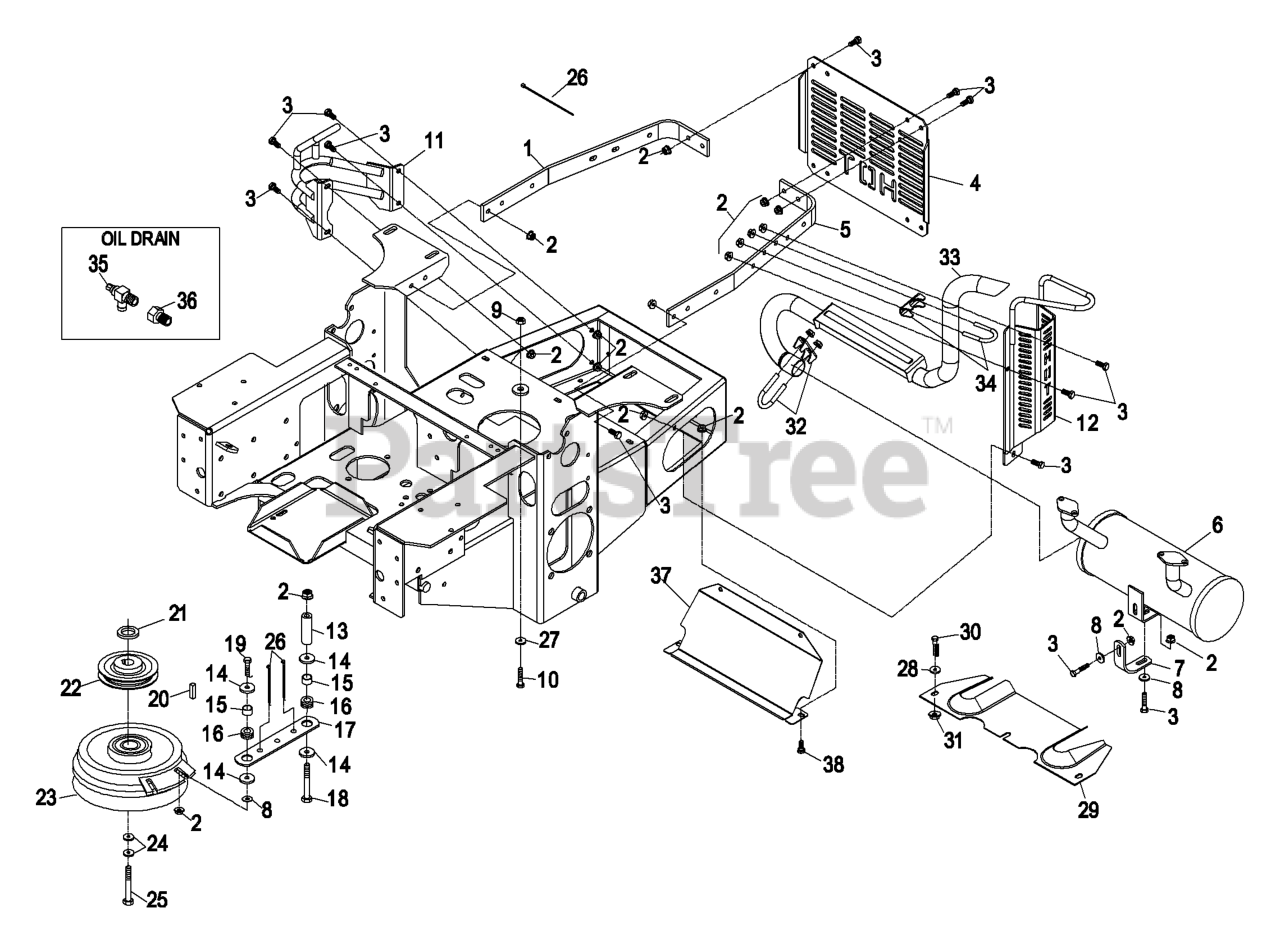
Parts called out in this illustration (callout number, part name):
1	STRAP-GUARD, RH
3	SCREW-HH
4	Shield, Eng. Guard
5	STRAP-GUARD, LH
6	KIT,MUFFLER LHP17KA
7	BRACKET-SUPPORT, MUFFLER
8	WASHER-FLAT
9	NUT-LOCK, NI
10	SCREW-HH
11	RH EXHAUST GUARD ASM
12	LH EXHAUST GUARD ASM
16	GROMMET
17	STRAP-CLUTCH, BRAKE
18	SCREW-HH
19	SCREW-HH
21	SPACER-CRANKSHAFT
24	WASHER-SPRING
25	SCREW-HH
26	TIE-PLASTIC
27	WASHER-SPRING
28	WASHER-PLAIN
29	SHIELD-HEAT
30	BOLT-CARR
31	NUT-LOCK, NI
33	TAILPIPE
35	VALVE-DRAIN, OIL
36	ADAPTER
37	SHIELD-HEAT
38	SCREW-HH
39	GASKET-EXHAUST
